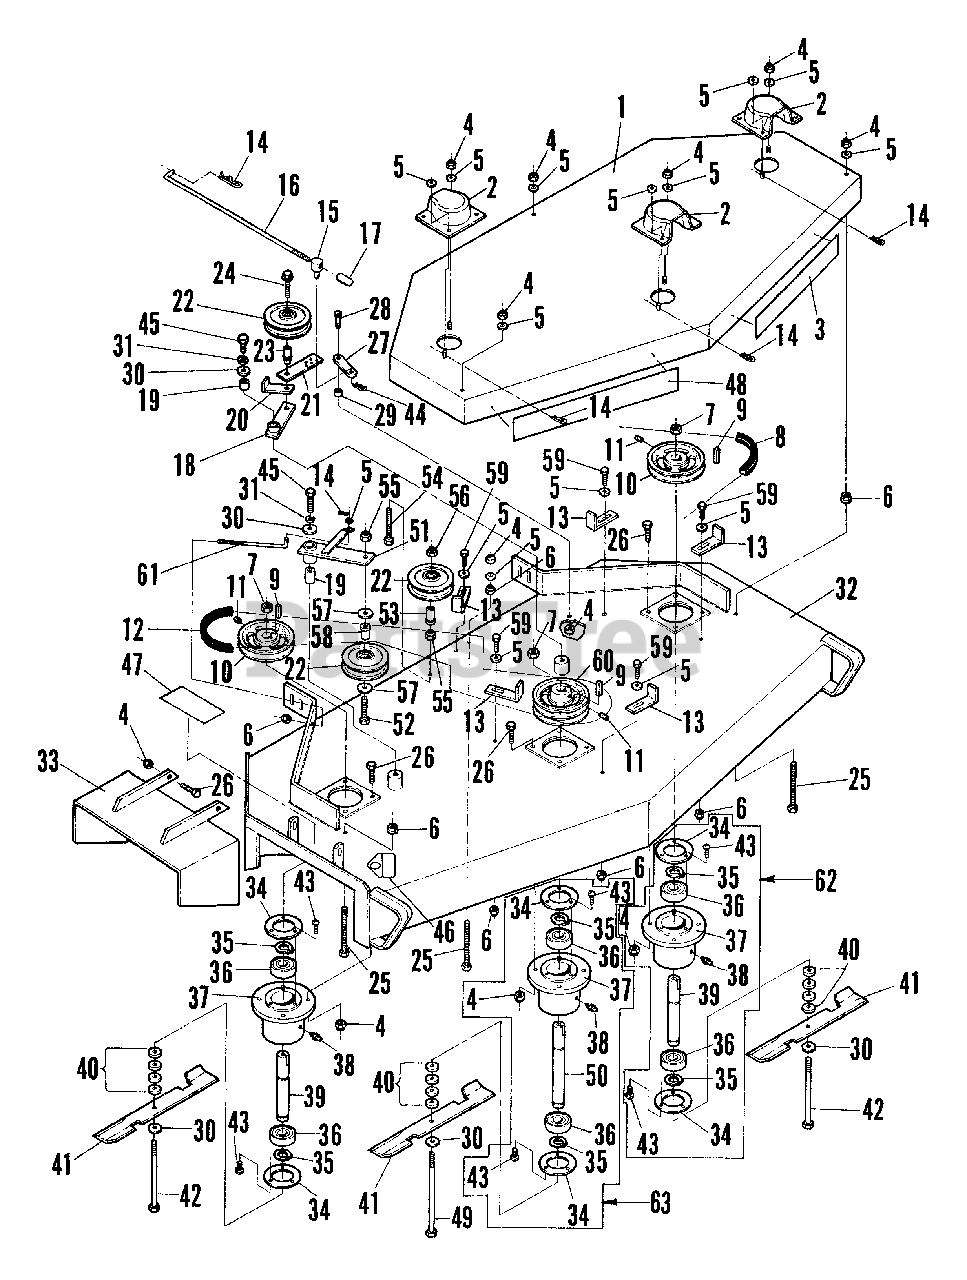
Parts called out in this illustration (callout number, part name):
1	SHIELD, Belt w/Decal 48
2	COVER, Spindle
3	DECAL, Commercial 48
4	NUT, 5/16-18 Hex Nyloc
5	WASHER, 5/16 Standard Flat
6	NUT, 5/16-18 Hex Flange Lock, Grade 5
7	NUT, 5/8-18 Hex
8	BELT, Engine/Blade
9	KEY, 1/4 Square x 1-1/4"
10	PULLEY, w/Set Screws
11	SCREW, Set
12	BELT, Blade to Blade
13	GUIDE, Belt
14	HAIRPIN, #2 Cotter
15	SWIVEL
16	ROD, Blade Drive
18	ARM, Idler w/Bushing
19	BUSHING
20	SNUBBER, Belt
21	ARM, Tightening
22	PULLEY, Idler
23	BUSHING, Flange
24	BOLT, 3/8-16 x 1-3/4" Hex Flange Lock, Grade 5
25	SCREW, 5/16-18 x 3-1/4" Hex Head Cap
26	SCREW, 5/16-18 x 1" Hex Head Cap, Grade 2
27	ARM, Blade Assist
28	BOLT, 3/8 x 3/4" Knurled Socket Head Shoulder
30	WASHER, 5/8" Flat
31	WASHER, 5/8" Split Lock
32	DECK, Front 48" w/Decals
33	DEFLECTOR, Chute
34	CAP, Cutter Housing
35	RING, Snap
36	BEARING
37	HOUSING, Cutter
38	FITTING, 1/8 NTP Grease
39	SPINDLE, Cutter
40	SPACER, Blade
41	BLADE, 16-1/4" Ultra High Lift (.164)
42	SCREW, 5/8-18 x 7-1/2" Hex Head Cap, Grade 5
43	SCREW, #10-24 x 3/8" Pan Head
44	HAIRPIN, #4 Cotter
45	SCREW, 5/8-11 x 1" Hex Head Cap, Grade 5
46	DECAL, CPSC
47	DECAL, "Caution"
48	DECAL, "SNAPPER"
49	SCREW, 5/8-18 x 8" Hex Head Cap, Grade 5
50	SPINDLE, Cutter
51	ARM, Idler Right w/Bushing
52	SCREW, 3/8-16 x 2" Hex Head Cap, Grade 5
53	BUSHING, Idler Flange
54	BOLT, 3/8-16 x 2-1/2" Hex Head Tap
55	NUT, 3/8-16 Hex Nyloc
56	NUT, 3/8-16 Hex Flange Lock
57	WASHER, 3/8" Flat
58	BUSHING, Idler Flange
59	SCREW, 5/16-18 x 3/4" Hex Head Cap, Grade 2
60	PULLEY, Double w/Set Screws
61	ROD, Belt Tension
62	ASSEMBLY, Cutter Housing
63	ASSEMBLY, Cutter Housing (Center)
